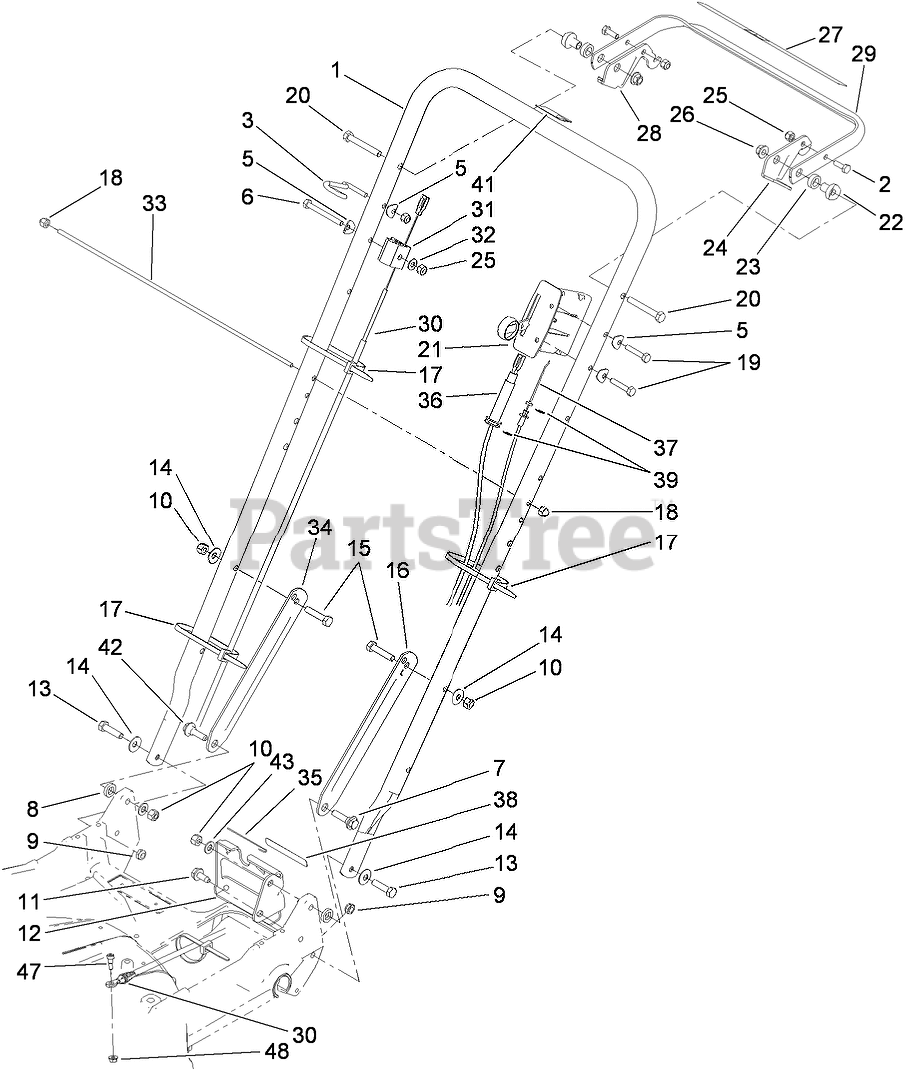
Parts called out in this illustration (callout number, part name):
2	SCREW-HH
3	GUIDE-ROPE
5	WASHER
6	SCREW-HH
7	SCREW-SHOULDER
8	SPACER
9	NUT-LOCK, NI
10	NUT-LOCK, NI
11	SCREW-HWHTF
12	BRACKET-ADJUSTMENT, TRACTION
13	SCREW-HH
14	WASHER-BELLEVILLE
15	SCREW-HH
16	LATCH-HANDLE, LH
17	TIE-CABLE
18	NUT-CAP
19	SCREW-HH
20	SCREW-HH
21	CONTROL-HEAD, THROTTLE
22	SPACER-SUPPORT
23	SPACER-NYLON
24	LEVER-CONTROL
25	NUT-LOCK, NI
26	NUT-LOCK, NI
27	Decal-Traction
28	LEVER-CONTROL
29	BAR-CONTROL
30	CABLE-BRAKE, CONTROL
31	SUPPORT-CABLE
32	WASHER-FLAT
33	ROD-SUPPORT, BAG
34	LATCH-HANDLE, RH
35	RETAINER-CABLE
36	CABLE-TRACTION
37	THROTTLE CABLE ASM
38	DECAL-POSITION, GEAR
39	E-RING
41	DECAL-PROTECTION, EAR
42	SCREW-SHOULDER
43	WASHER-PLAIN
47	SCREW-SHOULDER
48	NUT-LOCK, FLANGE
